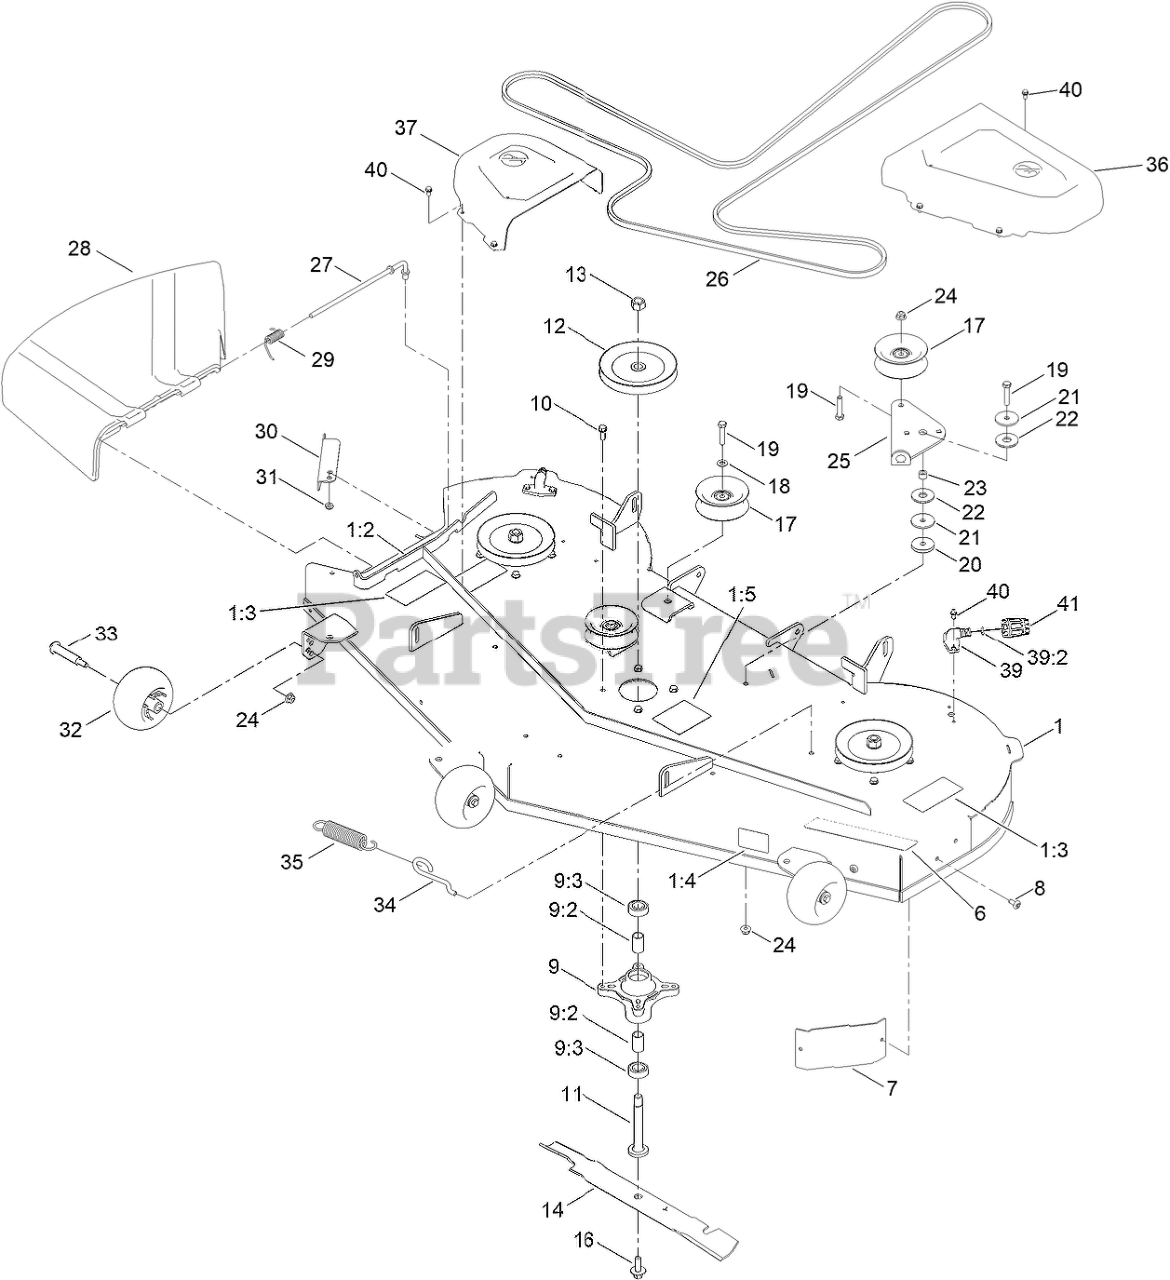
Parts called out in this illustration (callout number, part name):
1	60in DECK AND DECAL ASM
1:2	DECAL-DANGER
1:3	DECAL-DANGER, DECK
1:4	DECAL-SCALP, ANTI
1:5	DECAL-ROUTING, BELT
6	DECAL - DECK
7	BAFFLE-CORNER
9	SPINDLE ASM
9:2	SPACER
9:3	BEARING-BALL
10	SCREW-TAPTITE
11	SHAFT-SPINDLE
12	PULLEY
13	NUT-HEX
14	BLADE-HI FLOW, 20.5 INCH
16	BOLT-BLADE, SEMS
17	PULLEY-IDLER, FLAT
18	WASHER-FLAT
19	SCREW-HH
20	WASHER-PLAIN
21	WASHER-REBOUND
22	WASHER-FRICTION, COMPOSITE
23	SPACER
24	NUT-HF, NI
25	ARM-IDLER
26	BELT
27	ROD-PIVOT
28	DEFLECTOR-DISCHARGE
29	SPRING-TORSION
30	BAFFLE-CUTOFF
32	ROLLER-SCALP, ANTI
33	BOLT-SHOULDER
34	HOOK-RETURN SPRING
35	SPRING-EXTENSION
36	COVER-BELT, LH
37	COVER-BELT, RH
39	FITTING-WASHOUT
39:2	O-RING
40	SCREW-HWH
41	CONNECTOR-HOSE
